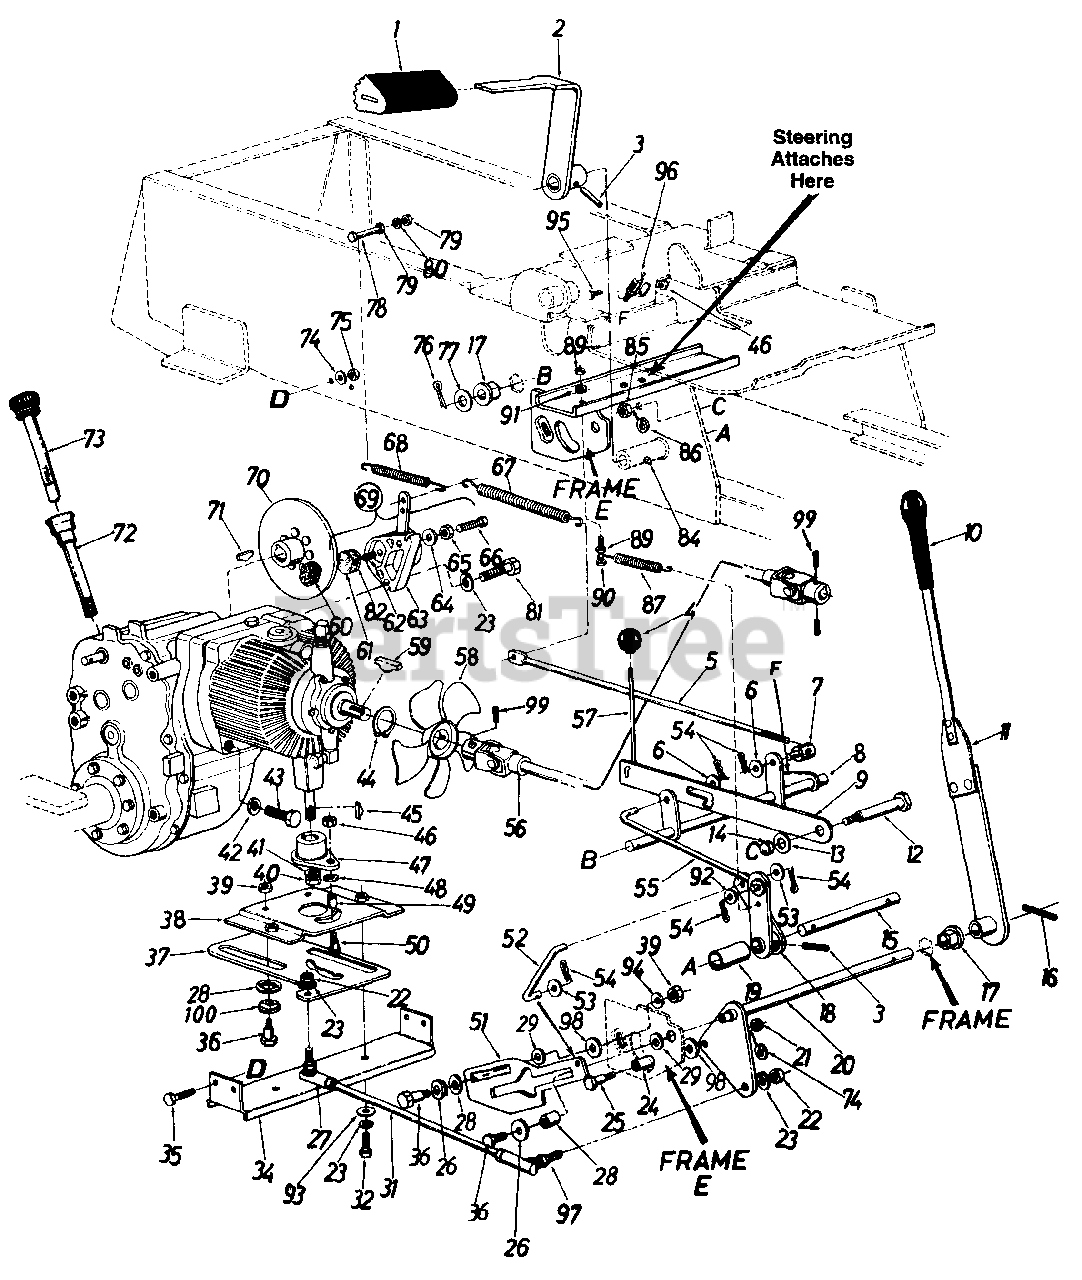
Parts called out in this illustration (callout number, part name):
6	Fl-Wash. .375" I.D. x 1.00" O.D. x .030"
7	Ferrule
8	Brake Transfer Shaft Ass'y.
9	Parking Brake Cam
11	Control Arm Ass'y. Comp.
12	Shld. Bolt .62" Dia. x 2.75" Lg.
13	Fl-Wash. .460" I.D. x 1.24" O.D. x .06"
14	Push Speed Nut for .625" Dia. Shaft
15	Brake Pivot Shaft
16	Spring Pin Spiral 1/4" Dia. x 1.50" Lg.
17	Hex Flange Brg. Plastic .62" I.D.
18	Brake Lever Ass'y.
20	Control Handle Shaft Ass'y.
21	Hex Cent. L-Nut 5/16-18 Thd.
22	Hex Nut 3/8-24 Thd.
23	L-Wash. 3/8" I.D.
25	Shoulder Bolt
26	Fl-Wash. 7/16" I.D. x 1-3/8" O.D.
27	Ball Joint Ass'y. 3/8-24 Thd. - L H.
29	Fl-Wash. .325" I.D. x 1.25" O.D.
31	Tie Rod
32	Hex Bolt 3/8-16 x .75" Lg.
34	Support Channel
35	Hex Bolt 5/16-18 x .75" Lg.
36	Shld. Bolt .437" Dia. x .268"
38	Slide Mtg. Plate Ass'y.
39	Hex Cent. L-Nut 5/16-18 Thd.
40	Hex Nut 1/2-13 Thd.
41	L-Wash. 1/2" I.D.
42	Fl-Wash. .385" I.D. x .87" O.D. x .060"
43	Socket Hd. Scr. 3/8-16 x 2.75" Lg.
45	#5 Hi-Pro Key 1/8" x 5/8" Dia.
46	Hex Cent. L-Nut 1/4-20 Thd.
47	Pintle Plate Assembly
48	Fl-Wash. .281" I.D. x .50" O.D. x .063"
49	Needle Brg. .31" I.D. x .50" O.D. x .437" Lg.
50	Shld. Bolt .31" Dia. x .500
51	Neutral Control Slide
52	Neutral Control Rod
53	Fl-Wash. .312" I.D. x .630" O.D. x .063"
54	Hairpin Cotter
55	Brake Link Rod Ass'y.
56	Universal Drive Shaft Comp.
57	Parking Brake Link
58	Fan Ass'y.
59	#61 Hi-Pro Key 3/16 x 5/8" Dia.
60	Lining - Brake
61	Lining - Brake
63	Housing with Lever and Pin
64	Washer
65	Nut
66	Adjustment Pin
67	Extension Spring .50" O.D. x 6.5" Lg.
68	Extension Spring
69	Disc Brake Ass'y. Comp.
70	Brake Disc Ass'y.
71	Hi-Pro Key 3/16 x 3/4" Dia.
72	Dipstick Tube Ass'y.
73	Dipstick Ass'y.
74	L-Wash. 5/16" I.D.
75	Hex Nut 5/16-18 Thd.
76	Cotter Pin 1/8" Dia. x 1.00" Lg.
77	Fl-Wash. .635" I.D. x 1.00" O.D. x .120" Thk.
78	Hex Scr. 1/4-20 x 2.50" Lg.
79	Hex Nut 1/4-20 Thd.
80	L-Wash. 1/4" I.D.
81	Hex Scr. 3/8-16 x 1.25" Lg.
82	Backing Plate
84	Grease Fitting
85	Hex Nut 7/16-20 Thd.
86	L-Wash. 7/16" I.D.
87	Extension Spring
89	Hex Nut 1/4-20 Thd.
90	Hex Bolt 1/4-20 x 1.25" Lg.
91	L-Wash. 1/4" I.D.
92	Fl-Wash.
93	Fl-Wash. .38" I.D. x 1.25" O.D.
95	Hex Bolt 1/4-20 x 1/2" Lg.
96	Safety Switch
97	Ball Joint Ass'y. 3/8-24 Thd. - R.H.
98	Fl-Wash. .32" I.D. x .6" O.D.
99	Set Screw 5/16-18 x .38" Lg.
100	Thrust Washer
